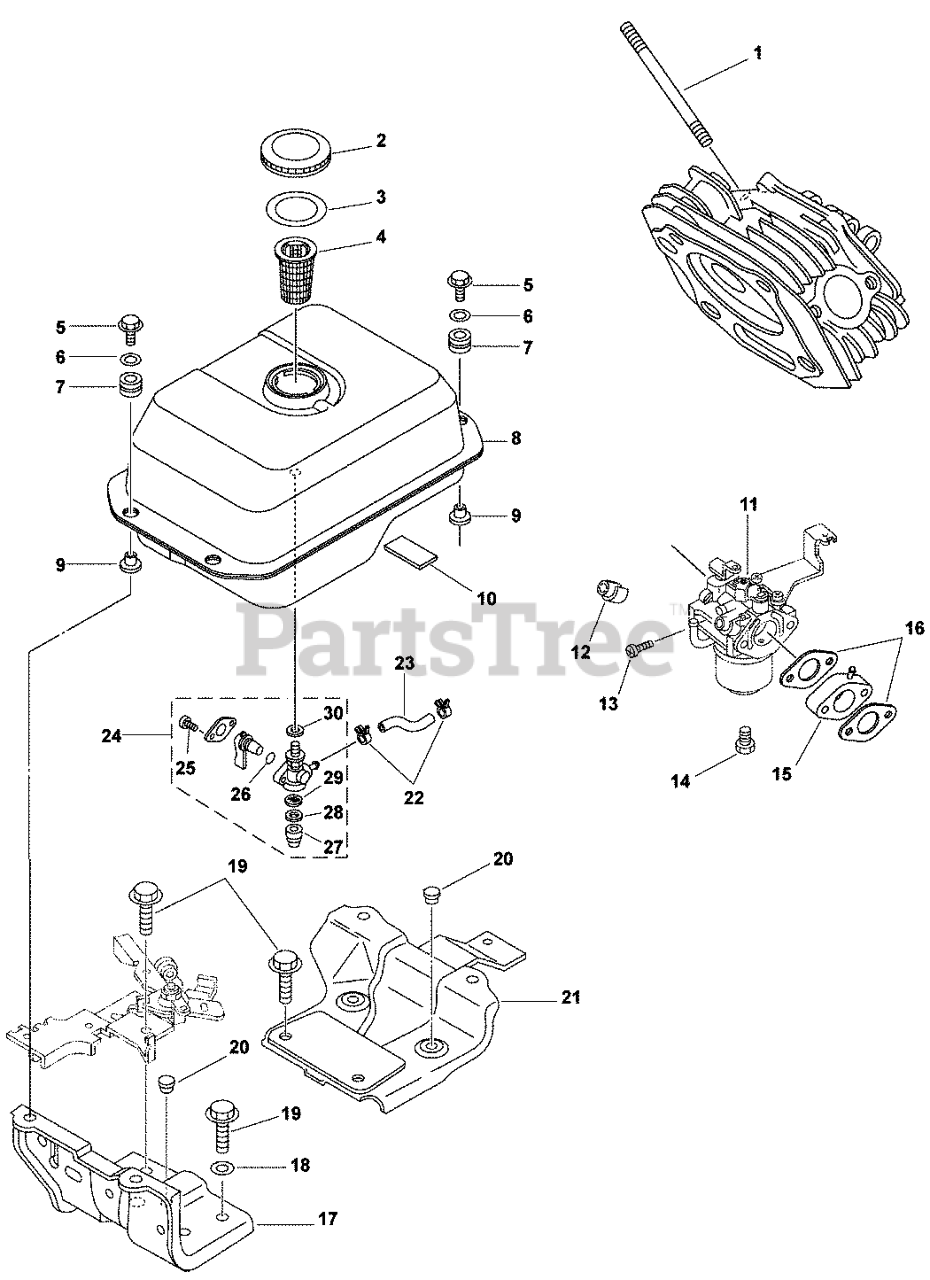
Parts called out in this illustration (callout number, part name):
2	CAP, FUEL TANK
3	SEAL, GAS CAP
8	FUEL TANK
10	DAMPER, LOCATING
11	KIT, CARBURETOR
12	CAP, CARBURETOR ADJUSTING
14	SCREW, FLOAT BOWL, L.F.
15	MANIFOLD, INTAKE
16	GASKET, INTAKE
17	BRACKET, TANK - FOR 600 SERIES
21	BRACKET, TANK 600 SERIES
24	VALVE, FUEL COCK ASSEMBLY
25	SCREW, PAN HEAD
26	O-RING, FUEL VALVE
27	CUP, FILTER
29	FILTER SCREEN
6375501-S	KIT, OVERHAUL (CS12)
6375702-S	CARB FLOAT KIT (CS 10 & 12)
